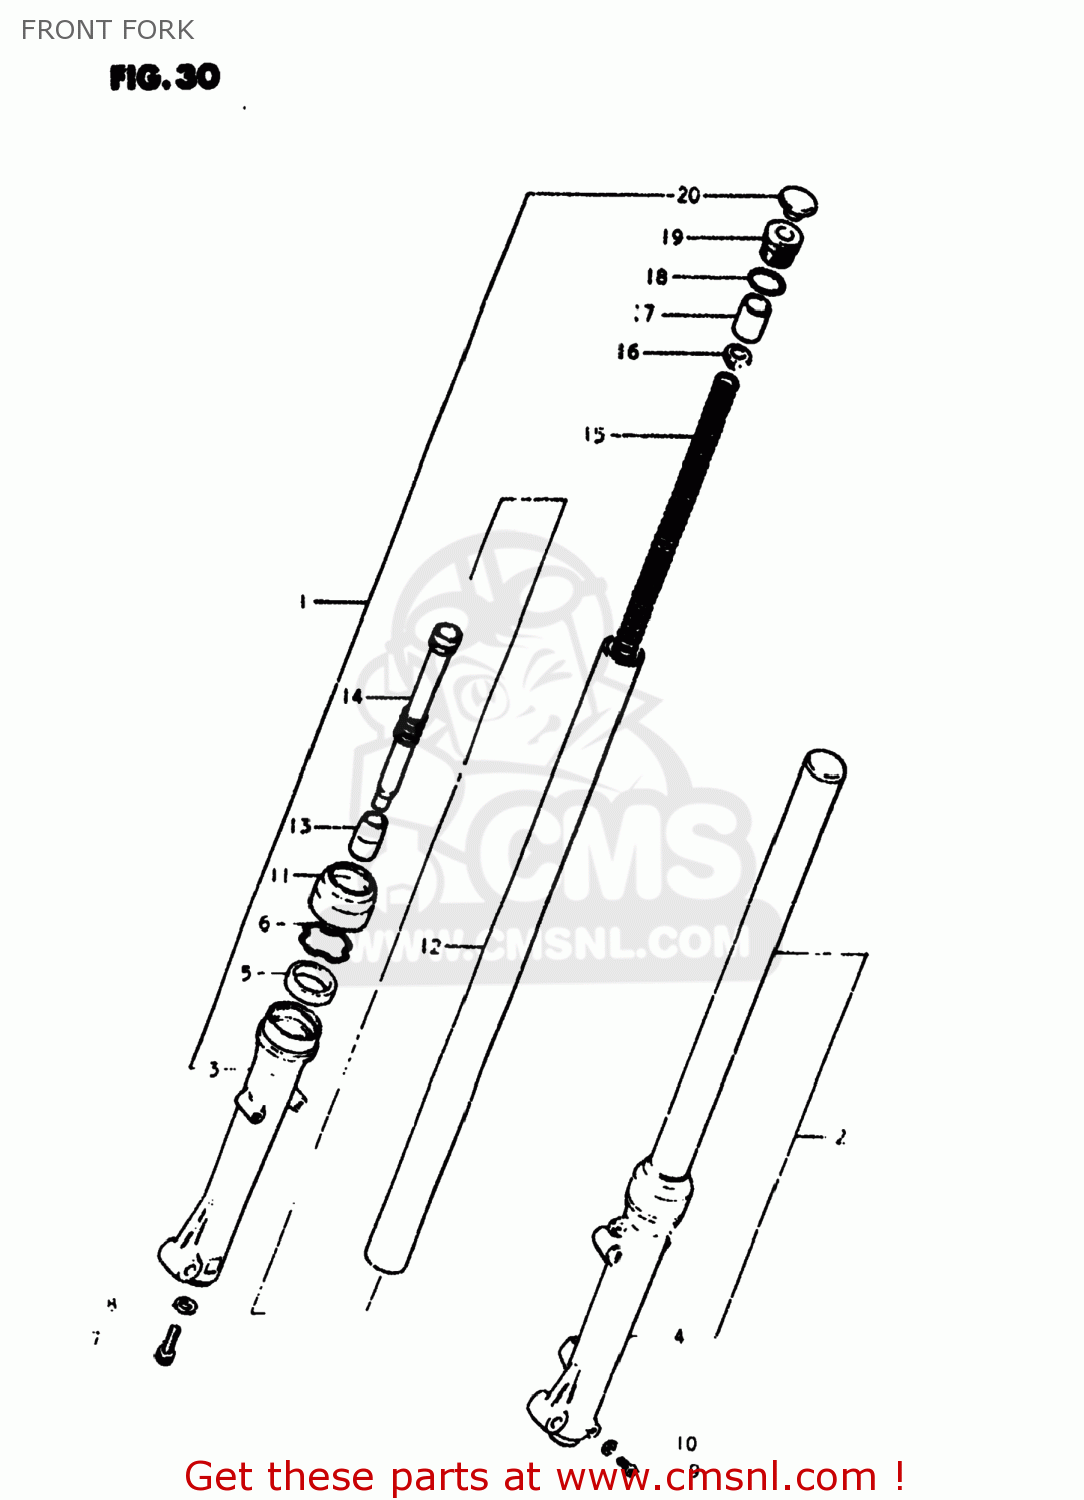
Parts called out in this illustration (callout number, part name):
1	DAMPER ASSEMBLY,RIGHT
2	DAMPER ASSEMBLY,LEFT
3	TUBE,OUTER,RIGHT
4	TUBE,OUTER,LEFT
5	OIL SEAL,FRONT FORK
6	7
7	BOLT,FORK CYLINDER(10X25)
8	GASKET (NAS)
9	SCREW
10	GASKET,DRAIN,PLUG (NAS)
11	SEAL,DUST
12	TUBE,FORK,INNER
13	PIECE,OIL LOCK
14	CYLINDER,FRONT FORK
15	SPRING
16	GUIDE,FRONT FORK SPRING C
17	SPACER,SPRING
18	O RING
19	CAP,FORK INNER TUBE
20	CAP,FRONT FORK
